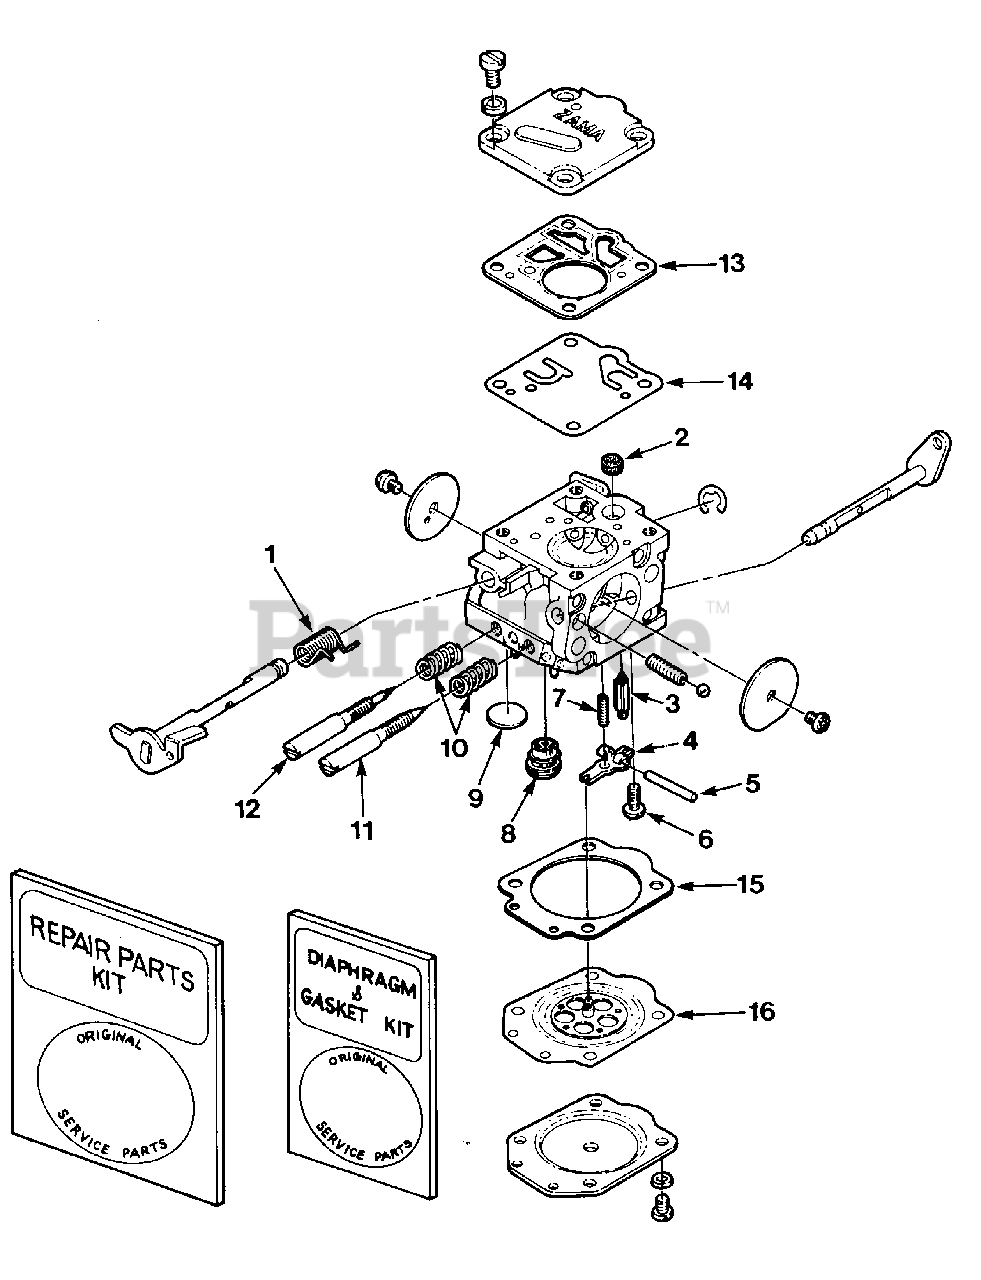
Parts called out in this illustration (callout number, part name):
1	Repair Kit
2	Repair Kit
3	Repair Kit
4	Repair Kit
5	Repair Kit
6	Repair Kit
7	Repair Kit
8	Repair Kit
9	Repair Kit
10	Repair Kit
11	Repair Kit
12	Repair Kit
13	Repair Kit
14	Repair Kit
15	Repair Kit
16	Repair Kit
